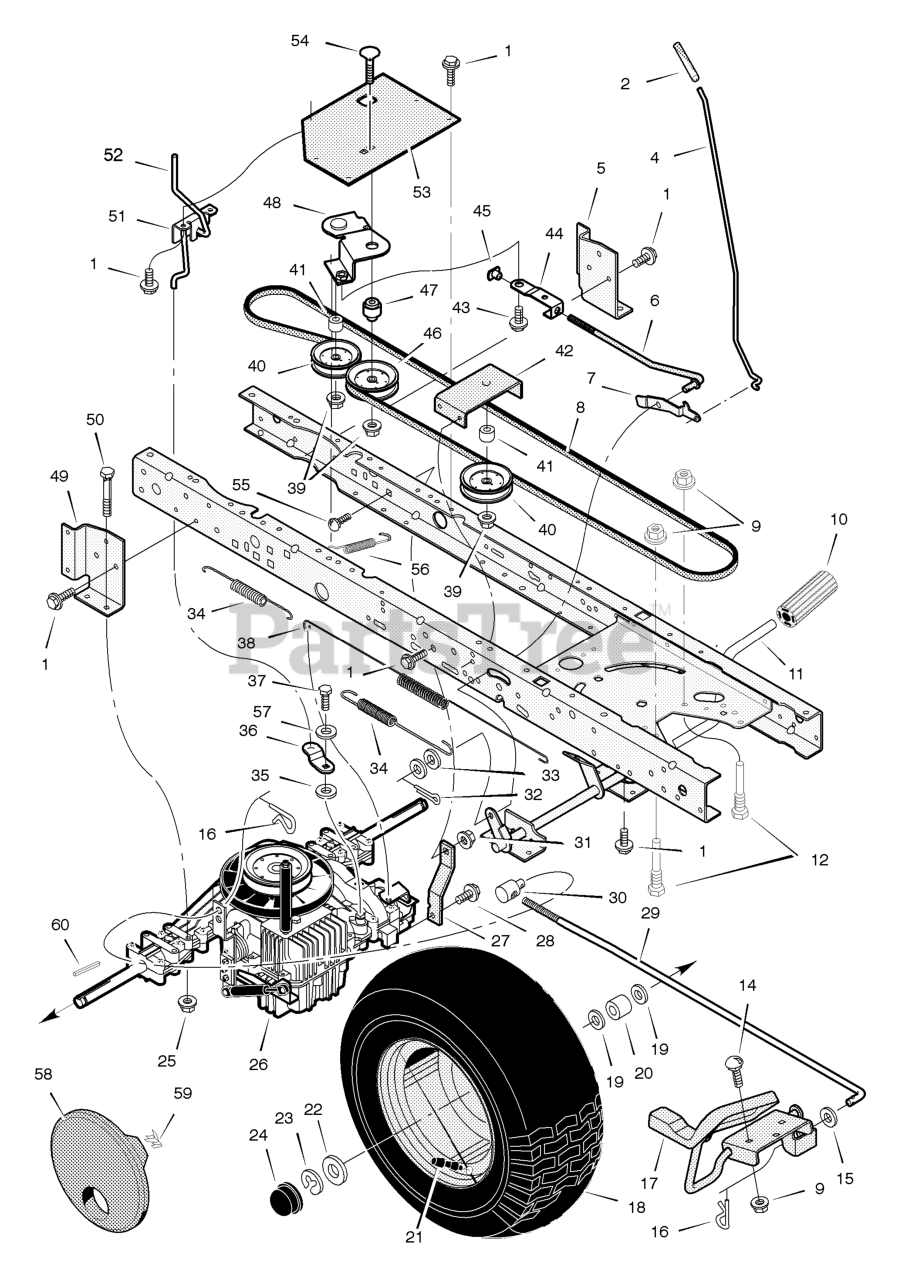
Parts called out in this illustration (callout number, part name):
2	Grip, Parking Brake
4	Rod, Parking Brake
5	Bracket, Transaxle - Left
6	Rod, Clutch
7	Latch, Parking Brake
8	V-Belt, Drive
9	Nut, Flange
10	Pedal, Brake/Clutch
11	Assembly, Brake Pedal
12	Screw, Guide
14	Bolt, Carriage
16	Pin, Hair
17	Pedal Assembly, Hydro
18	Wheel & Tire Ass'y - Rear 20"
20	Spacer
21	Stem, Valve
24	Cap, Hub
25	Nut, Centerlock
26	Transaxle **
27	Strap, Torque
29	Rod, Control
30	NUT, Adjusting, 1/2-13
31	Nut, Centerlock
32	Pin, Cotter
34	Spring, Extension
36	ARM, Disconnect
37	Capscrew
38	Spring, Brake
39	Locknut, Flange
40	Pulley, Idler
42	Bracket, Idler Assembly
43	Bolt, Shoulder
44	Link, Clutch
45	Nut, Tee
46	Pulley, Idler
47	Bushing, Pivot
48	Arm Assembly, Idler
49	Bracket, Transaxle -Right
50	Bolt, Hex
51	Bracket, Disconnect
52	Rod, Disconnect
53	Bracket, Idler Pivot
54	Bolt, Carriage
55	Bolt, Carriage
56	Spring, Clutch
58	Cap, Hub
59	Retainer
60	Key, Square
